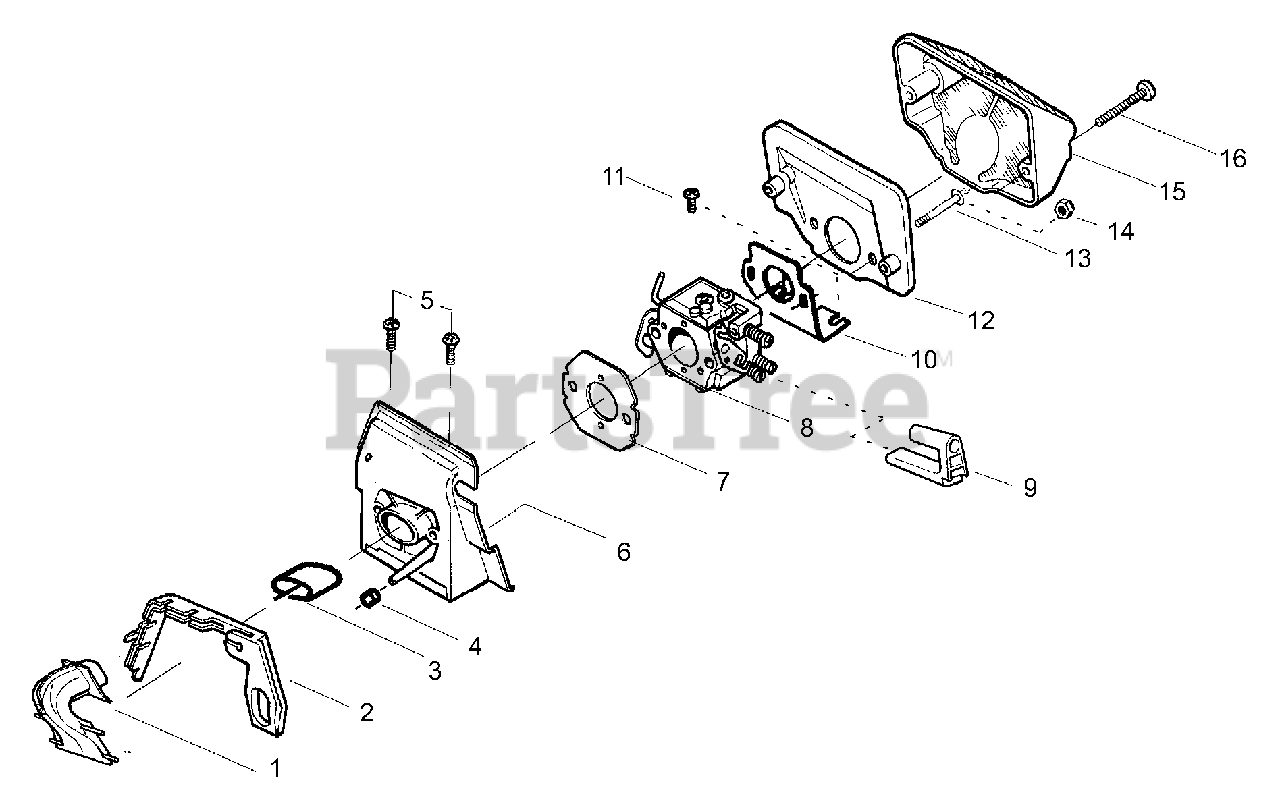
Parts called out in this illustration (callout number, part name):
1	Turbo Air Cleaner Assembly
2	Seal - Turbo Clean
3	Intake Sleeve
4	Impulse Seal
6	Adapter - Carb.
7	Carburetor Gasket
8	Carburetor WT-542 (Walbro)
8	Carburetor WT-289 (Walbro)
9	Grommet-Final
10	Plate - Support
12	Air Filter - Bottom
13	Stud - Carb.
15	Air-Filter - Top
